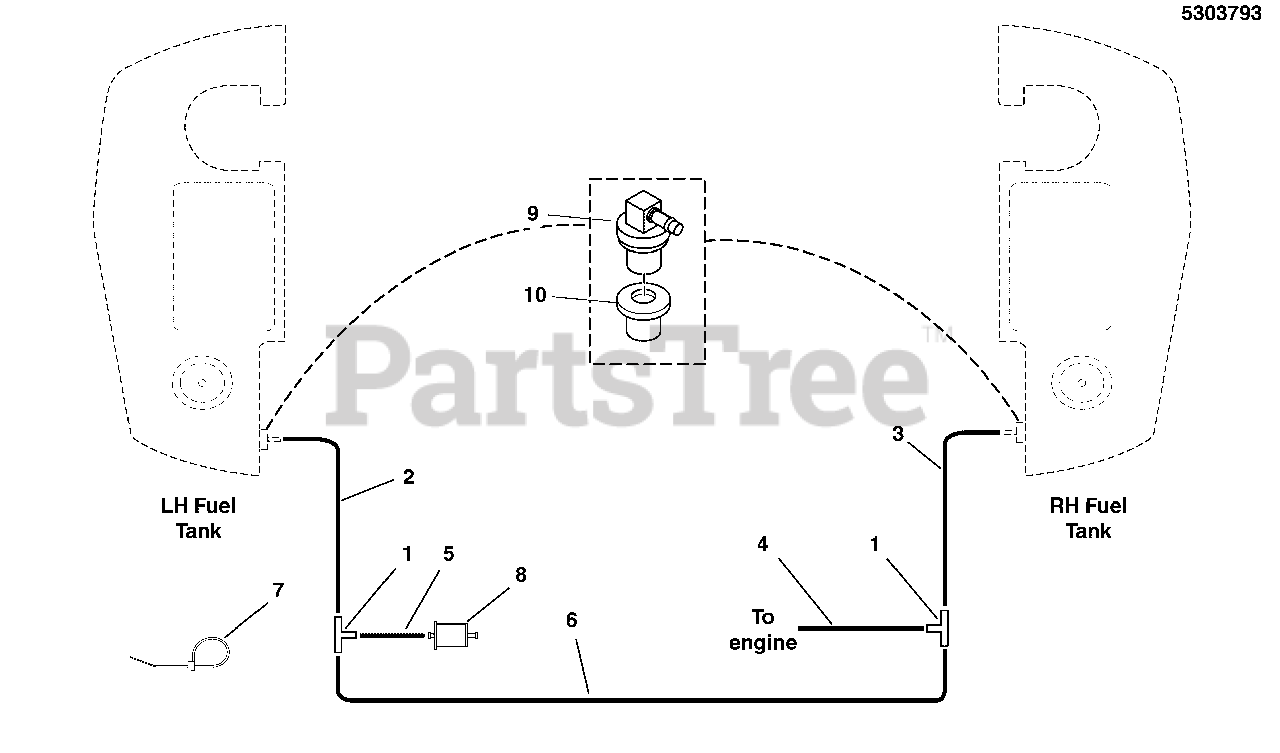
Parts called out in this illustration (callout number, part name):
1	FITTING, 3/16" TEE, BARB TYPE, HDPE
2	HOSE, VAPOR, 5MM ID, 33.00 LG
3	HOSE, VAPOR, 5MM ID, 24.50 LG
4	HOSE, VAPOR, 5MM ID, 9.00 LG
5	HOSE, VAPOR, 5MM ID, 2.00 LG
6	HOSE, VAPOR, 5MM ID, 7.00 LG
7	TIE,SELF-LOCKING, 6"
8	FILTER, FUEL
9	REMOTE VENT ASSEMBLY
10	GROMMET (SV)
